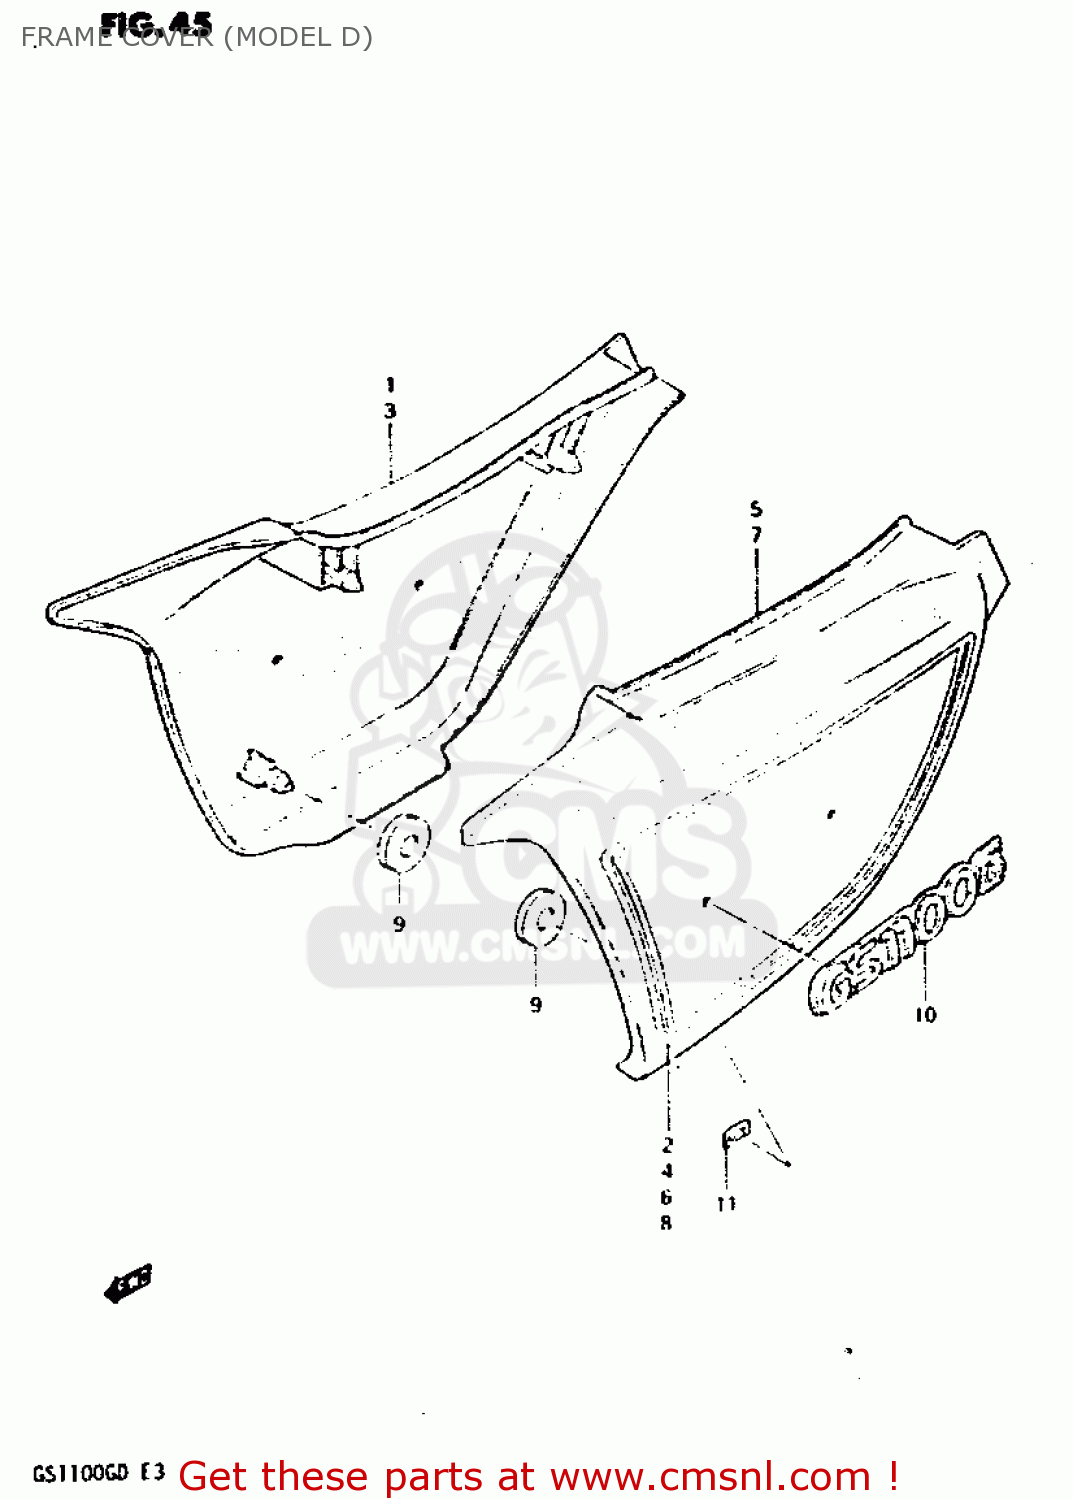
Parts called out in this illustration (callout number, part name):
1	COVER,FRAME,R
2	TAPE SET,FRAME COVER
3	COVER,FRAME,RIGHT
4	TAPE SET,FRAME COVER
5	COVER,FRAME,LEFT
6	TAPE SET,FRAME COVER
7	COVER,FRAME,LEFT
8	TAPE SET,FRAME COVER
9	CUSHION
10	EMBLEM,FRAME COVER
11	NUT
